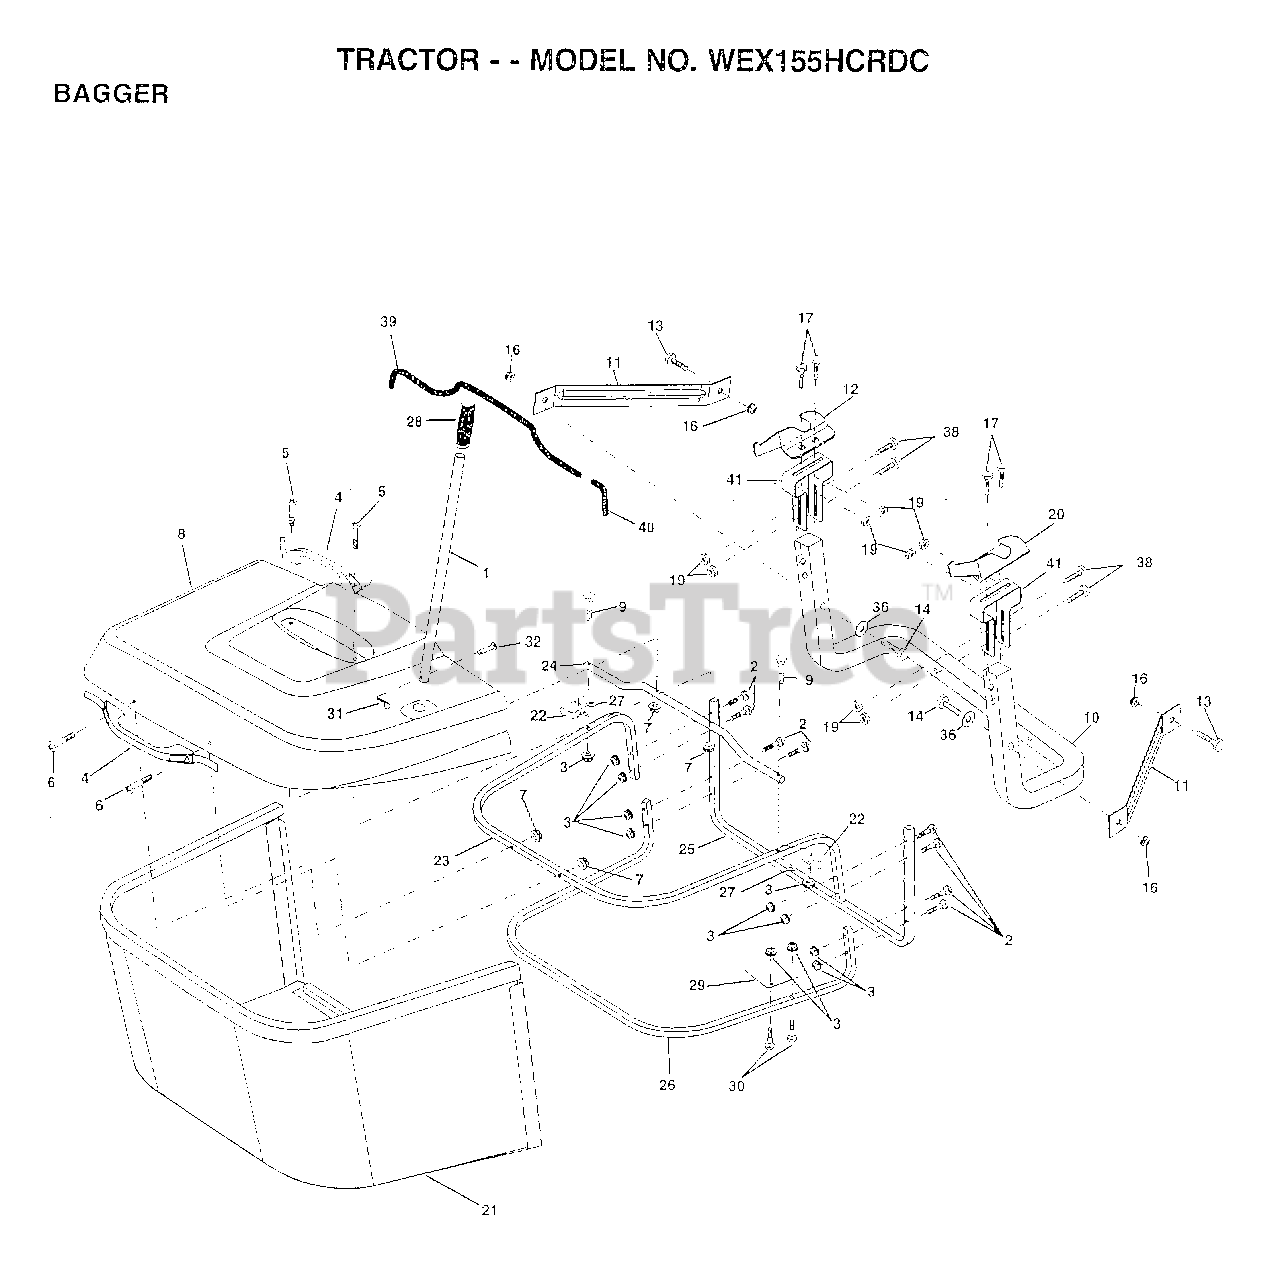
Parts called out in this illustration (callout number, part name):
1	TUBE.HDLE.BAG.CRD
2	BOLT.CARRIAGE.1/4-20X2.0
4	HANDLE BAGGER
5	"SCREW,PAN.HEAD"
7	NUT.WIZ.LOCK
8	COVER.BAGGER.CRD
9	BOLT CARRIAGE
10	TUBE SUPPORT BAGGER CRD
11	BRKT.SUPT.UPPER.BAG.CRD
12	BRACKET HORIZ ADJ BGGR LH CRD
13	BOLT
14	BOLT.HEX.3/8-16X2-1/2
17	BOLT
19	"NUT HEX,LOCK,FLAN"
20	BRACKET HORIZ ADJ BGGR RH CRD
21	BAG.ASM.CRD
22	BRKT.SIDE.BAG.CRD
23	TUBE.UPPER.BAG.CRD
24	TUBE.PIVOT.BAG.CRD
25	TUBE.FT.BAG.CRD
26	TUBE.LOWER.BAG.CRD.
27	BUSHING SNAP BAGGER CRD
28	GRIP.HANDLE.BLACK
29	PLATE.STOP.BAG.HDLE.CRD
30	BOLT.CARRIAGE
31	RETAINER M
32	RIVET.DRILL.1.75
38	BOLT.5/16-18X2.5
41	BRACKET VERT ADJ BAGGER CRD
